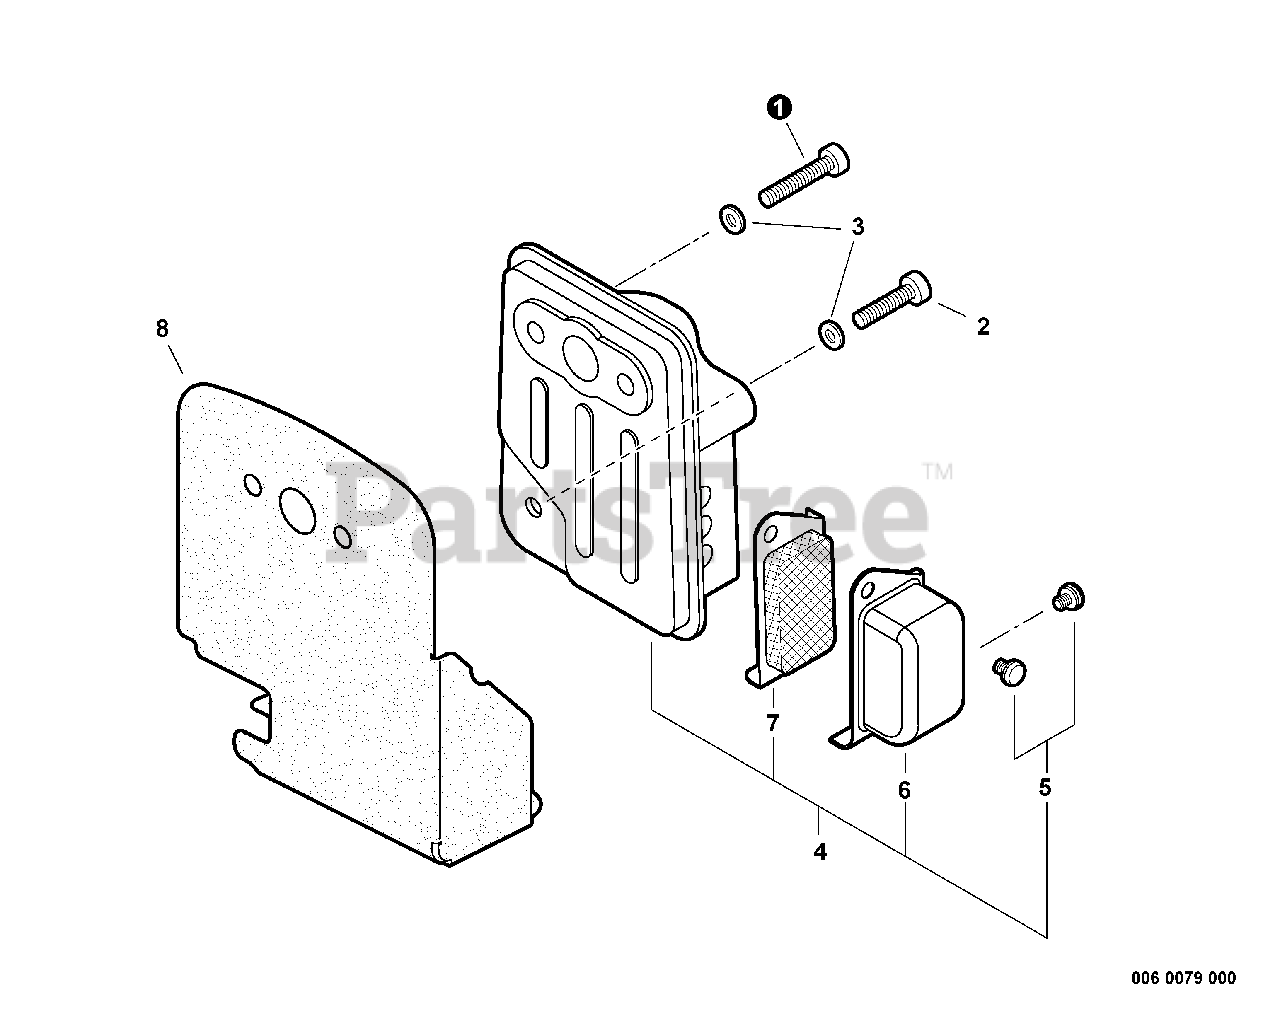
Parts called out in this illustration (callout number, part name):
1	BOLT M5×25
2	BOLT 5×16
3	WASHER, FLAT 5.5×10×0.8
4	MUFFLER ASSY
5	SCREW M4×6
6	GUIDE, EXHAUST
7	SCREEN, SPARK ARRESTER
8	HEAT SHIELD, EXHAUST
